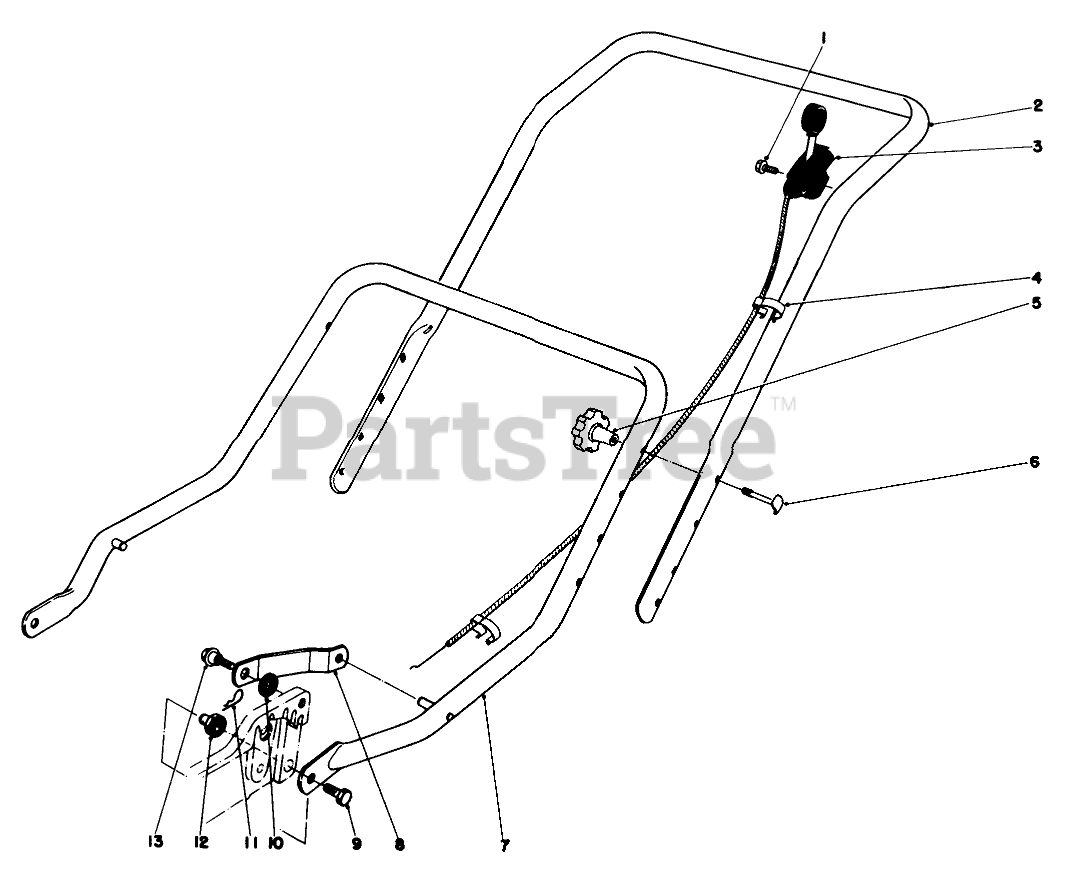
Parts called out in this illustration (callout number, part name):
2	Upper Handle
3	Throttle Control
4	BOWDEN CLIP
6	HANDLE SCREW
7	Lower Handle
8	HANDLE LATCH
9	SCREW-HH
10	SPACER
11	PIN-COTTER, HAIR
12	HANDLE PIVOT NUT
13	SCREW-SHOULDER
